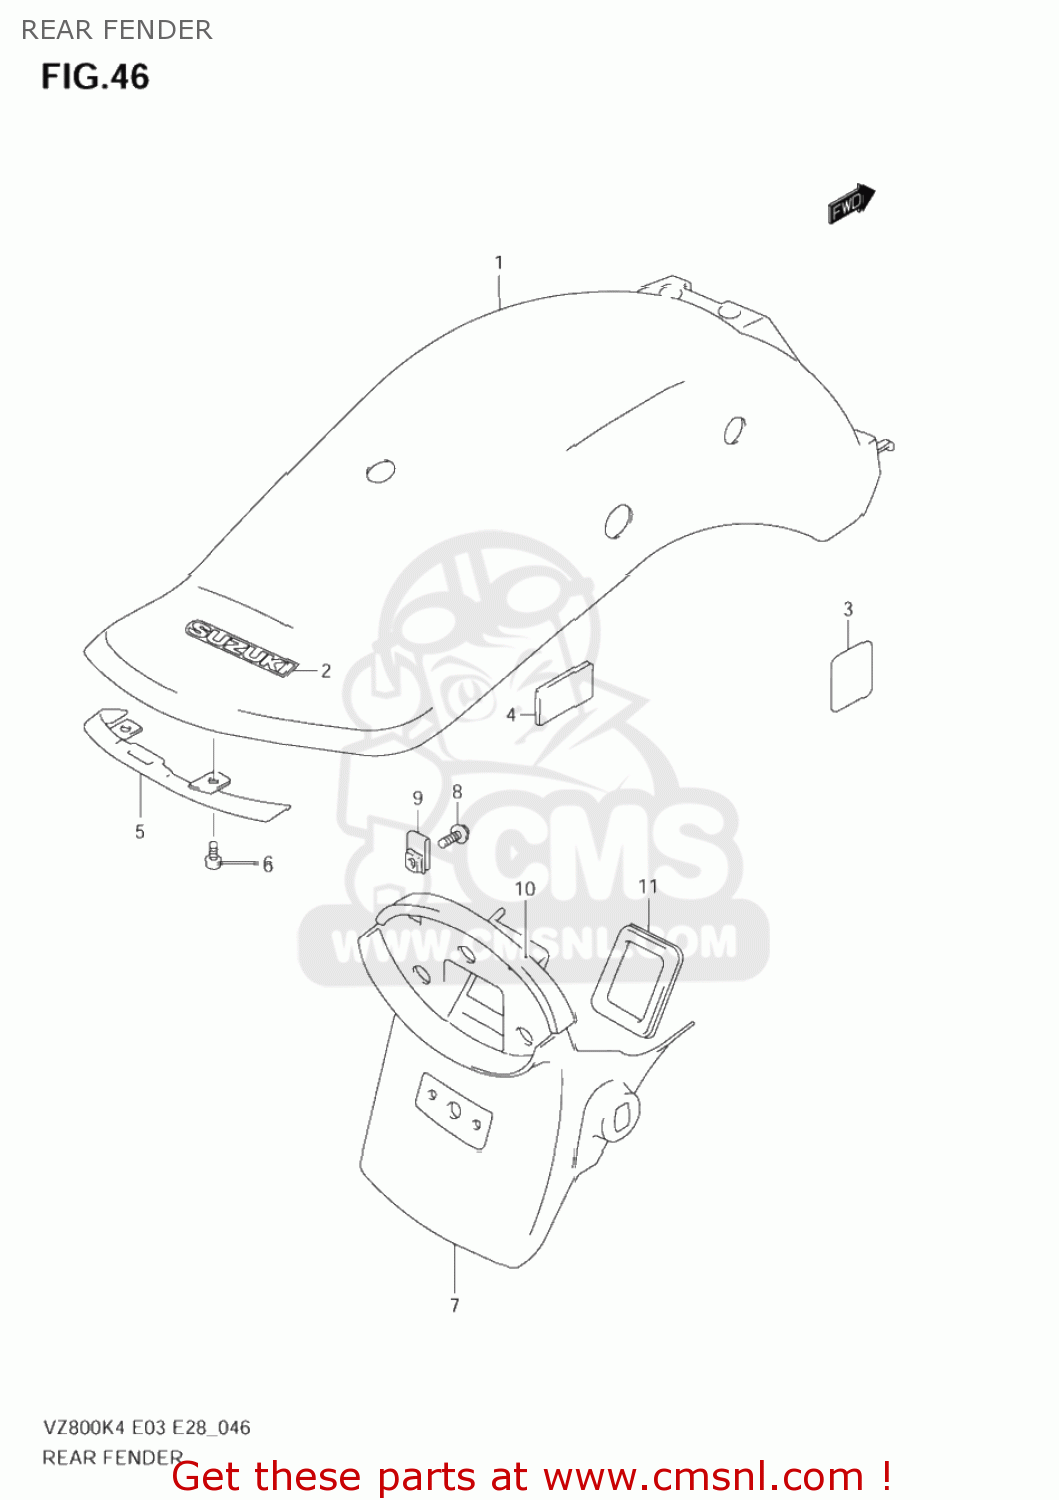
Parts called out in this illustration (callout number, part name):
1	FENDER,RR
2	EMBLEM,SUZUKI
3	PAD
4	CUSHION
5	COVER,RR FENDER RR
6	SCREW
7	EXTENSION,RR FENDER
8	SCREW
9	PLATE,FRAME COVER
10	CUSHION,RR FENDER EXTENSION
11	CAP,RR FENDER EXTENSION
